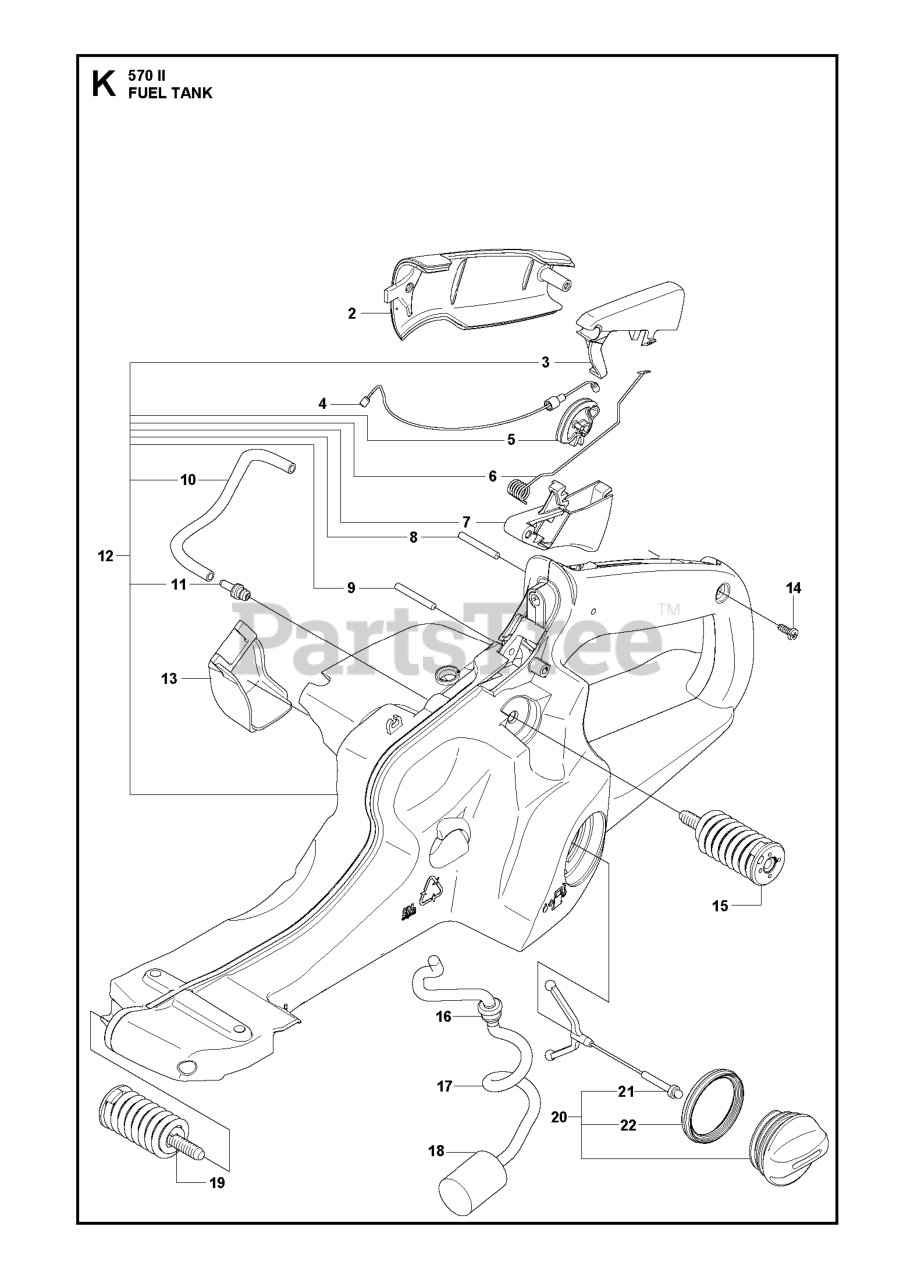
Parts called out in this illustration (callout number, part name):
2	COVER
3	THROTTLE LOCK
4	THROTTLE WIRE
7	THROTTLE TRIGGER
8	PIN 3X25
9	PIN 3X25
10	FUEL HOSE STRAIGHT 105
11	FUEL TANK VENT
15	VIBRATION ABSORBER
16	FUEL TANK BUSHING
17	FUEL HOSE SPIRAL 300
18	RP FUEL FILTER
19	VIBRATION ABSORBER
20	TANK CAP
